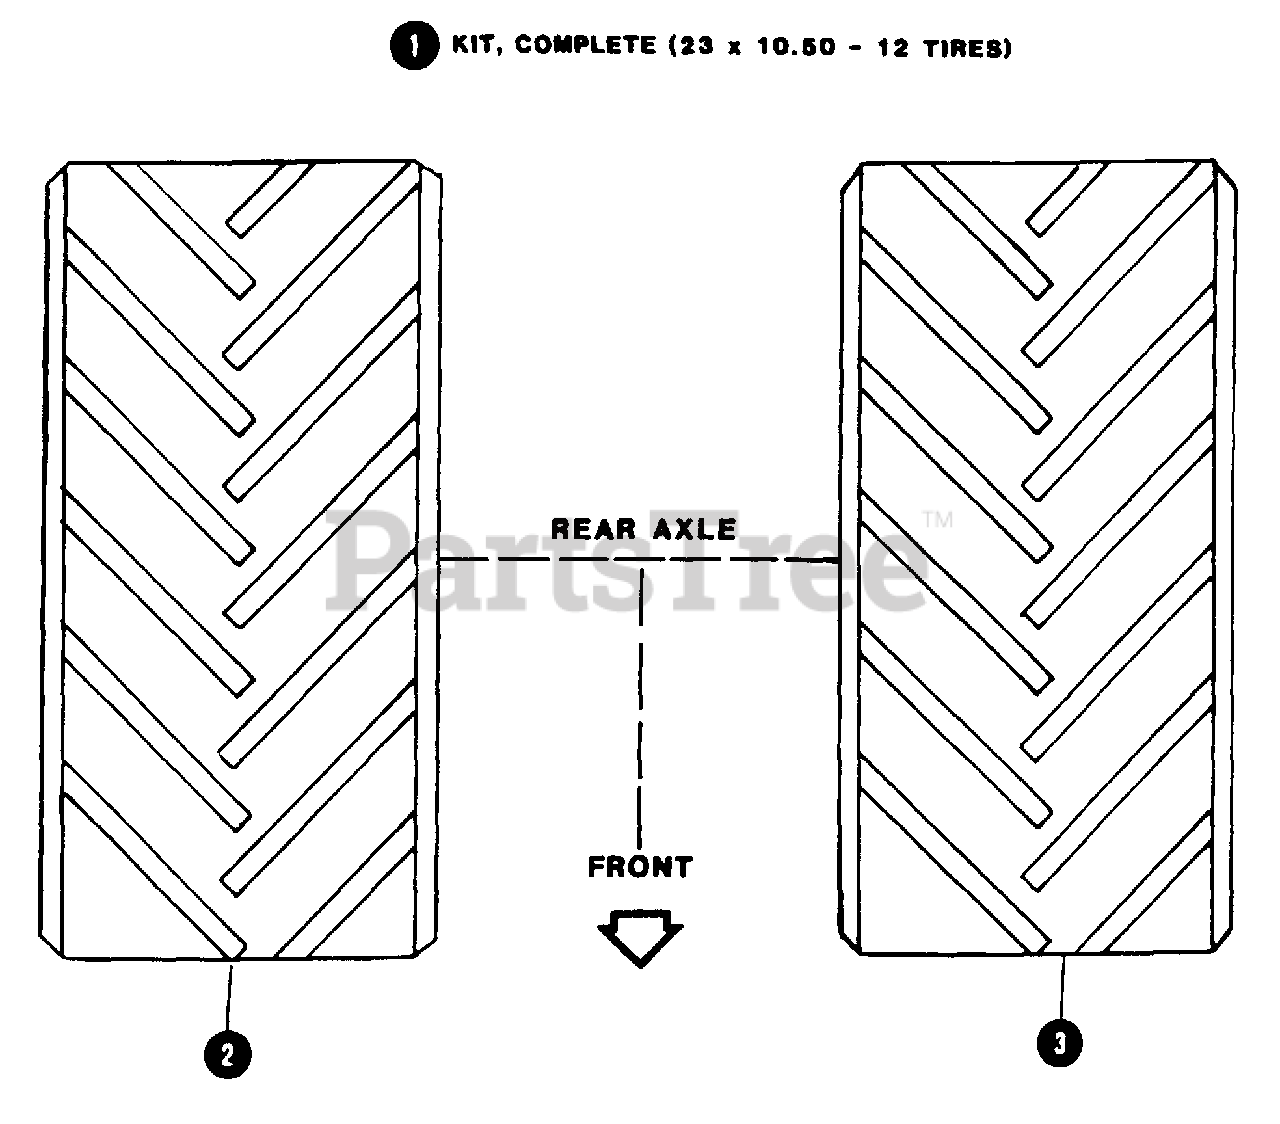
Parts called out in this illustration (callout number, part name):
1	KIT, AG REAR TIRE
2	WHEEL & TIRE ASSEMBLY - RIGHT SIDE
3	WHEEL & TIRE ASSEMBLY - LEFT SIDE
